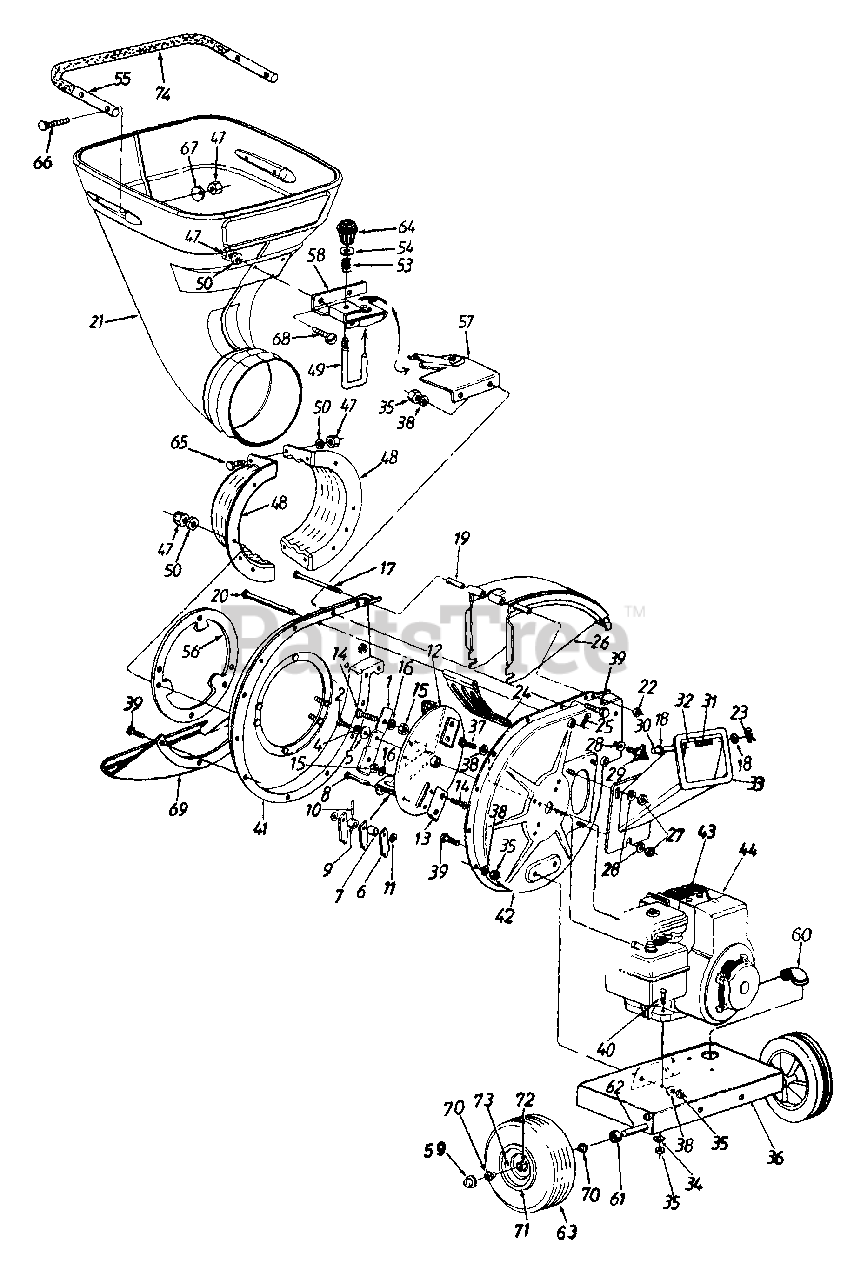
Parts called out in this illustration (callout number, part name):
1	Blade
2	Hex Patch Bolt 3/8-24 x 2.25" Lg.
4	L-Wash. 3/8" I.D. H.D.
5	FI-Wash..406" I.D. x 1.25" O.D. Hdn.
6	Flail
7	Flail Spacer
8	Clevis Pin .496" Dia.
9	Flail Spacer w/.160" Dia. Hole
10	Spring Roll Pin 1.12" Lg.
11	Fl-Wash .531" I.D. x .94" O.D.
12	Impeller Ass'y. Comp.
13	Chipper Blade
14	Flat Hd. Scr. 5/16-24 x .75" Lg.
15	Hex Top L-Nut 5/16-24 (Gr. 5)
16	L-Wash. 5/16" I.D.
17	Hex Bolt 1/4-20 x 3.75" Lg.
18	FI-Wash .281" I.D. x .50" O.D.
19	Chute Hinge Spacer 1.66" Lg.
20	Clevis Pin .5" Dia. x 4.62" Lg.
21	Rotating Hopper
22	Hex Ctr. L-Nut 1/4-20 Thd.
23	Cotter Pin
25	Internal Cotter Pin 3/8" Dia.
27	Hex Nut 5/16-18 Thd. (Gr. 5)
28	Bell-Wash. .345" I.D. x .88"
29	Hand Knob
30	Chipper Door Rod
31	Torsion Spring 1.14" Lg.
35	Hex Nut 5/16-18 Thd. (Gr. 5)
37	Hex Bolt 5/16-24 x .75" Lg.
38	L-Wash. 5/16" I.D.
39	Hex Bolt 5/16-18 x .75" Lg. (Gr. 5)
40	Hex Bolt 5/16-18 x 1.5" Lg.
44	Engine
47	Elastic Lock Nut 5/16-18 Thd.
48	Hopper Mtg. Collar
49	Locking Pin
50	Fl-Wash. 5/16" I.D.
53	Spring 1.5" Lg.
54	Fl-Wash .385" I.D. x .62" O.D.
60	Drain Elbow
61	Spacer .64" I.D. x .38" Lg.
62	Shredder Axle
64	Knob
65	Hex Bolt 5/16-18 x 1" Lg. (Gr. 5)
66	Curved Carr. Bolt 5/16-18 x 1.25" Lg.
67	Saddle Wash .32" I.D.
68	Carr. Bolt 5/16-18 x .75" Lg.
70	Flange Bearing .632" I.D.
73	Air Valve
74	Foam Grip
